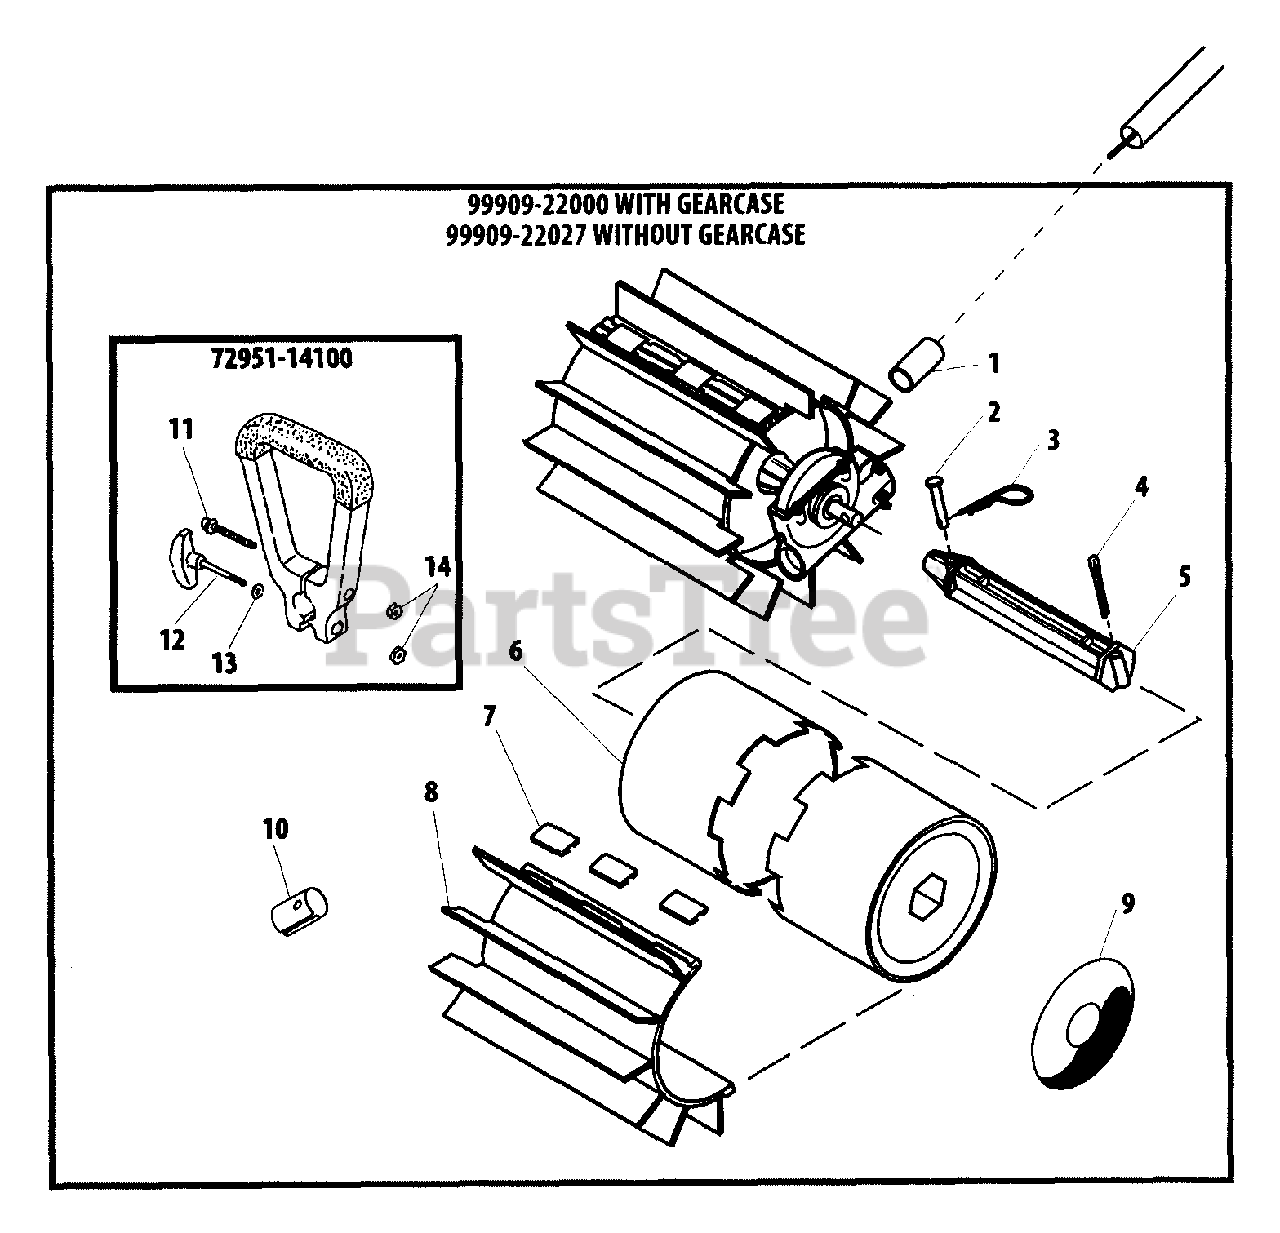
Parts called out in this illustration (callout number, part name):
1	TUBE PROTECTOR
2	CLEVIS PIN
3	PIN, HITCH
4	PIN, COTTER
5	AXLE, DRUM
6	HUB, DRUM
7	CLIP, BELT
8	BELT
10	SPACER
11	SCREW 6
12	KNOB, SCREW
13	WASHER 6
14	NUT, HEX M6
72951-14100	HANDLE ASSY
99909-22000	POWERBROOM CONVERSION KIT
99909-22027	B & D WITHOUT GEAR CASE
